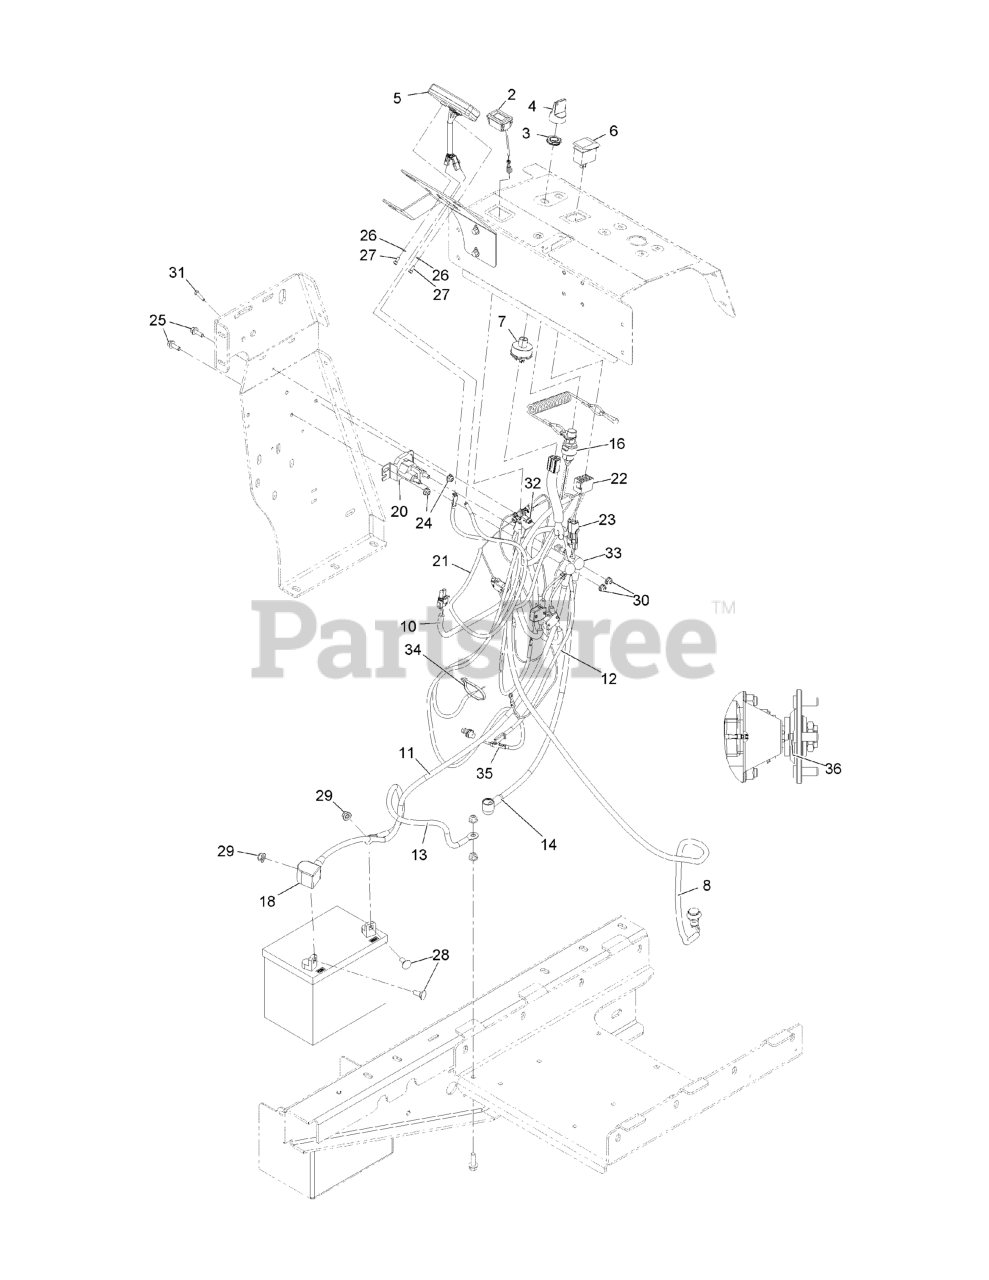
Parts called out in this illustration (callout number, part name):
2	METER-TACH/HOUR
3	NUT-SWITCH, KEY
4	KEY-UMBRELLA
5	HEAD ONLY, STRIKER
6	SWITCH-ROCKER
7	SWITCH-IGNITION
8	Switch-Push Button
10	Harness, Main
11	CABLE-POSITIVE
12	Wire-Solenoid
13	CABLE-GROUND
14	CABLE-POSITIVE
16	SWITCH-OP
18	Insulator-Battery
20	Solenoid-Starter
21	HARNESS-STRIKER
22	CONNECTOR-CARLING, 8F
23	Connector-Wp,2M
24	Nut-Hex Flange
25	Screw-HHF
26	WASHER-FLAT
27	SCREW-HSH
28	SCREW-CARR
29	Nut-Hex Flange
31	SCREW-HH
32	Nut-Hex Flange
33	INSULATOR-SOLENOID
34	TIE-CABLE
35	Cable-Trail Tech, Sensor
36	MAGNET, SPEEDOMETER
